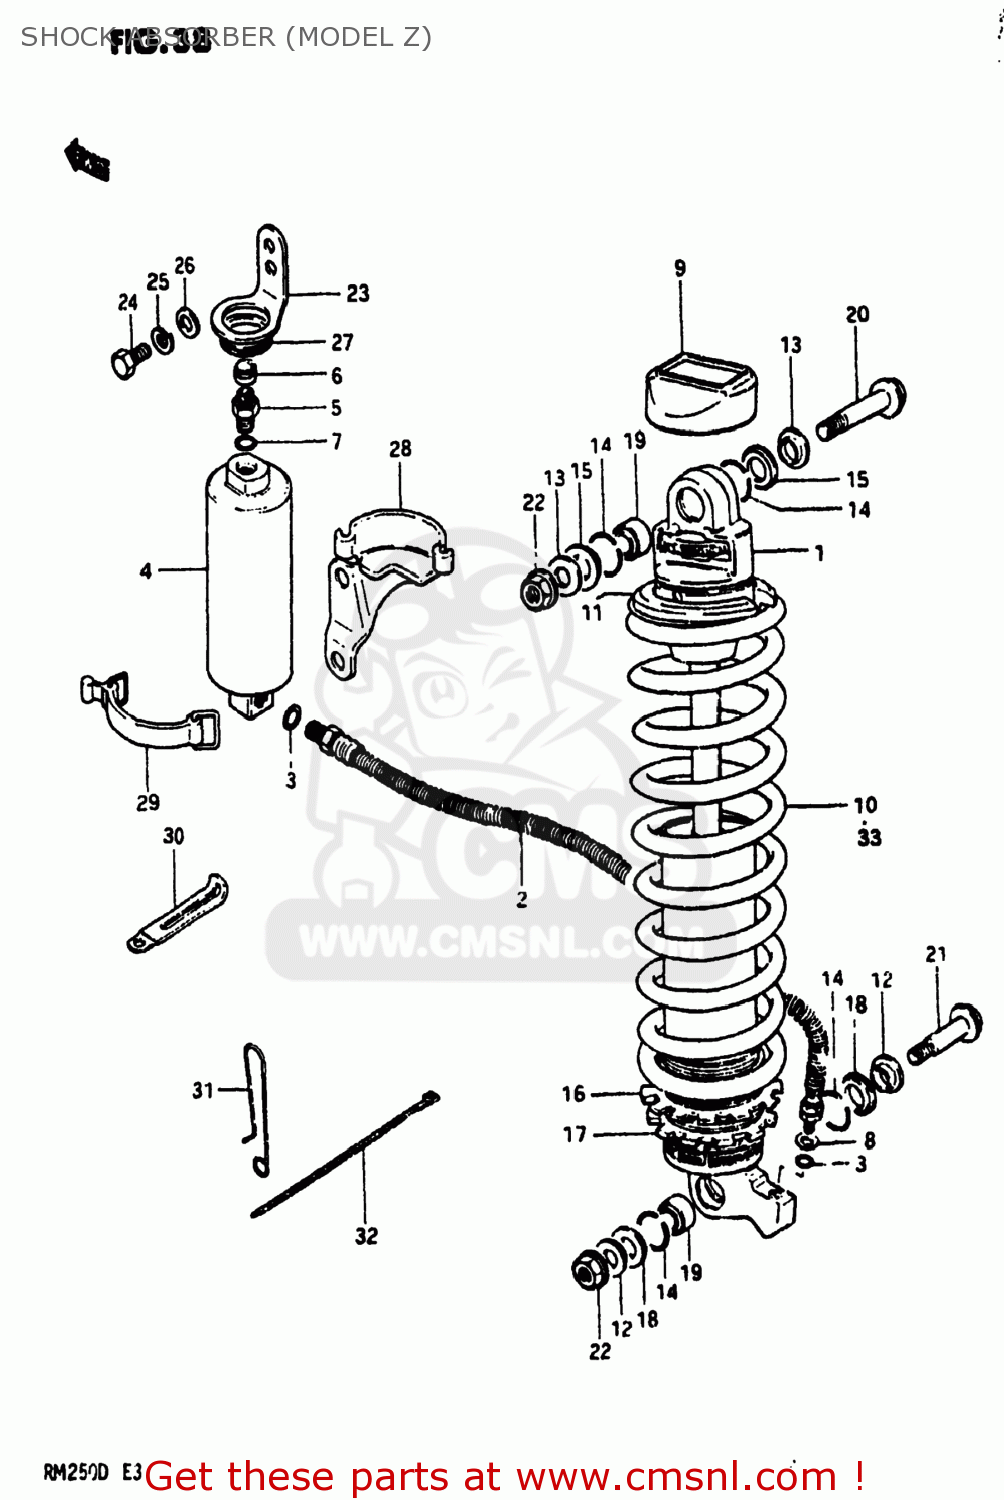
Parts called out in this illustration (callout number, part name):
1	ABSORBER ASSEMBLY,REAR SHOCK
2	HOSE,REAR SHOCK ABSORBER
3	O-RING,RESERVE TANK
4	RESERVE TANK,REAR SHOCK
5	VALVE ASSEMBLY,REAR CUSHION
6	CAP,VALVE AIR
7	O RING
8	WASHER,REAR SHOCK HOSE
9	CAP REAR SHOCK
10	SPRING
11	SPRING, GUIDE
12	COLLAR
13	SPACER,REAR SHOCK,UPPER
14	RING
15	DUST SEAL,UPR
16	GUIDE,SPRING
17	GUIDE,REAR SHOCK ABSORBER SPRING
18	DUST SEAL,LWR
19	BEARING
20	BOLT
21	BOLT(10X54)
22	NUT
23	BRACKET,RESERVOIR TANK
24	BOLT
25	LOCK WASHER
26	WASHER
27	CUSHION,RESERVOIR TANK
28	BRACKET,RESERVOIR TANK
29	BAND
30	CLAMP
31	GUIDE RES HOSE CLAMP
32	CLAMP
33	SPRING
